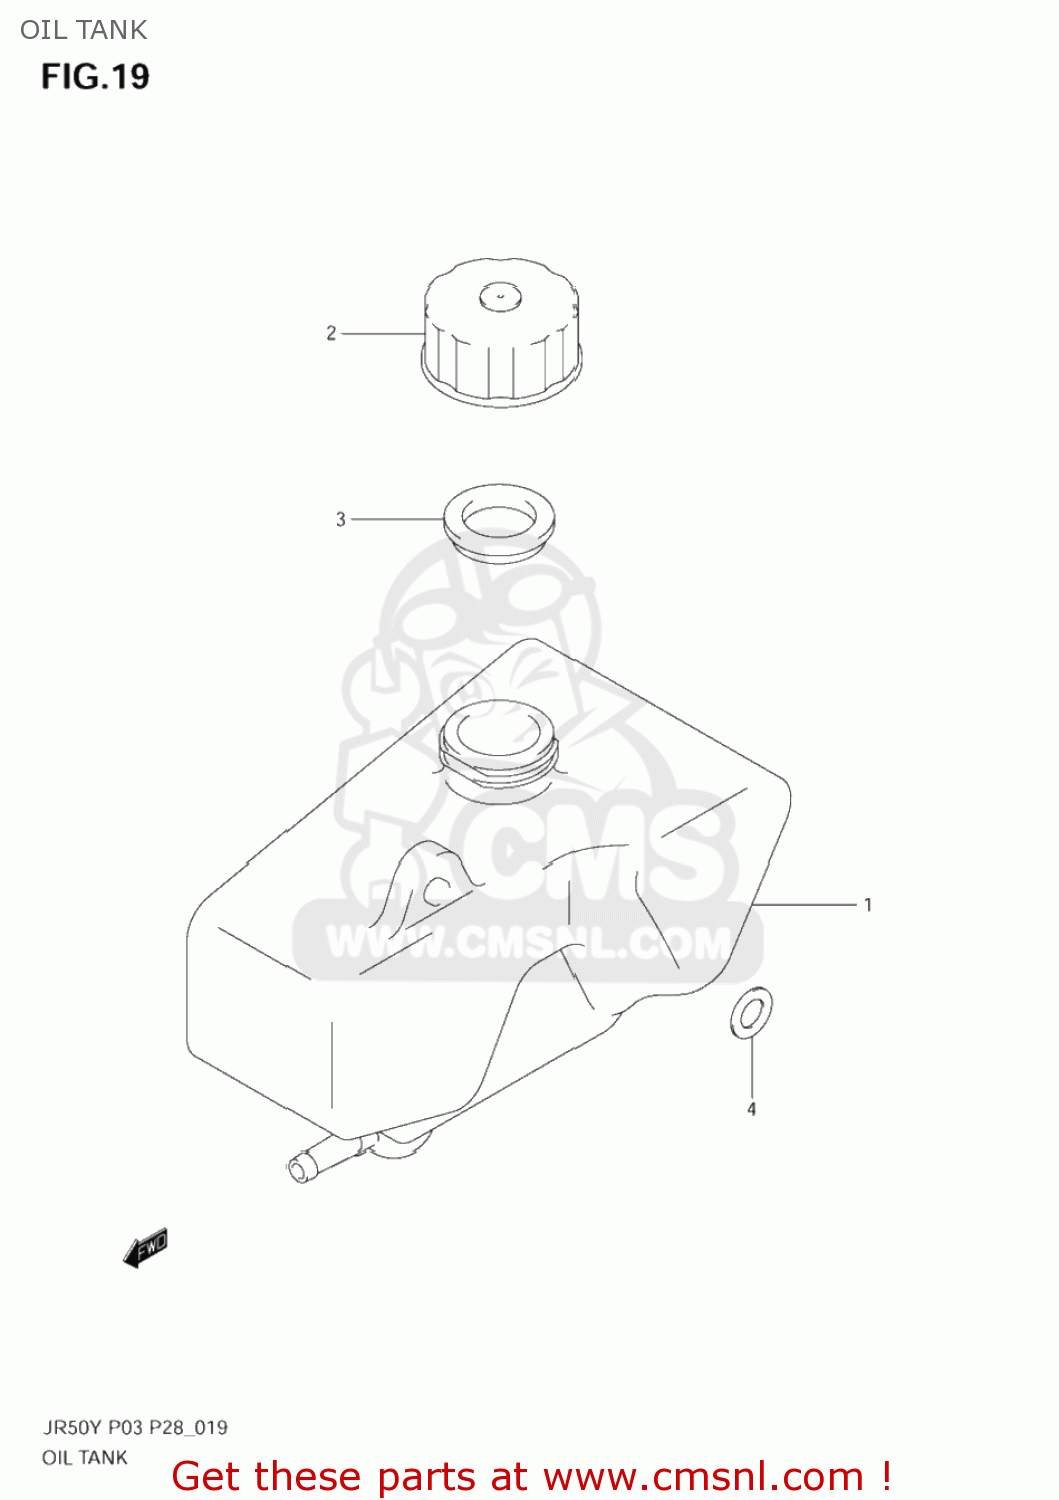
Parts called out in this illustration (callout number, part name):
1	TANK,OIL
2	CAP,OIL TANK FILLER
3	GASKET,OIL TANK CAP (NAS)
4	WASHER(10.5X18X1)
